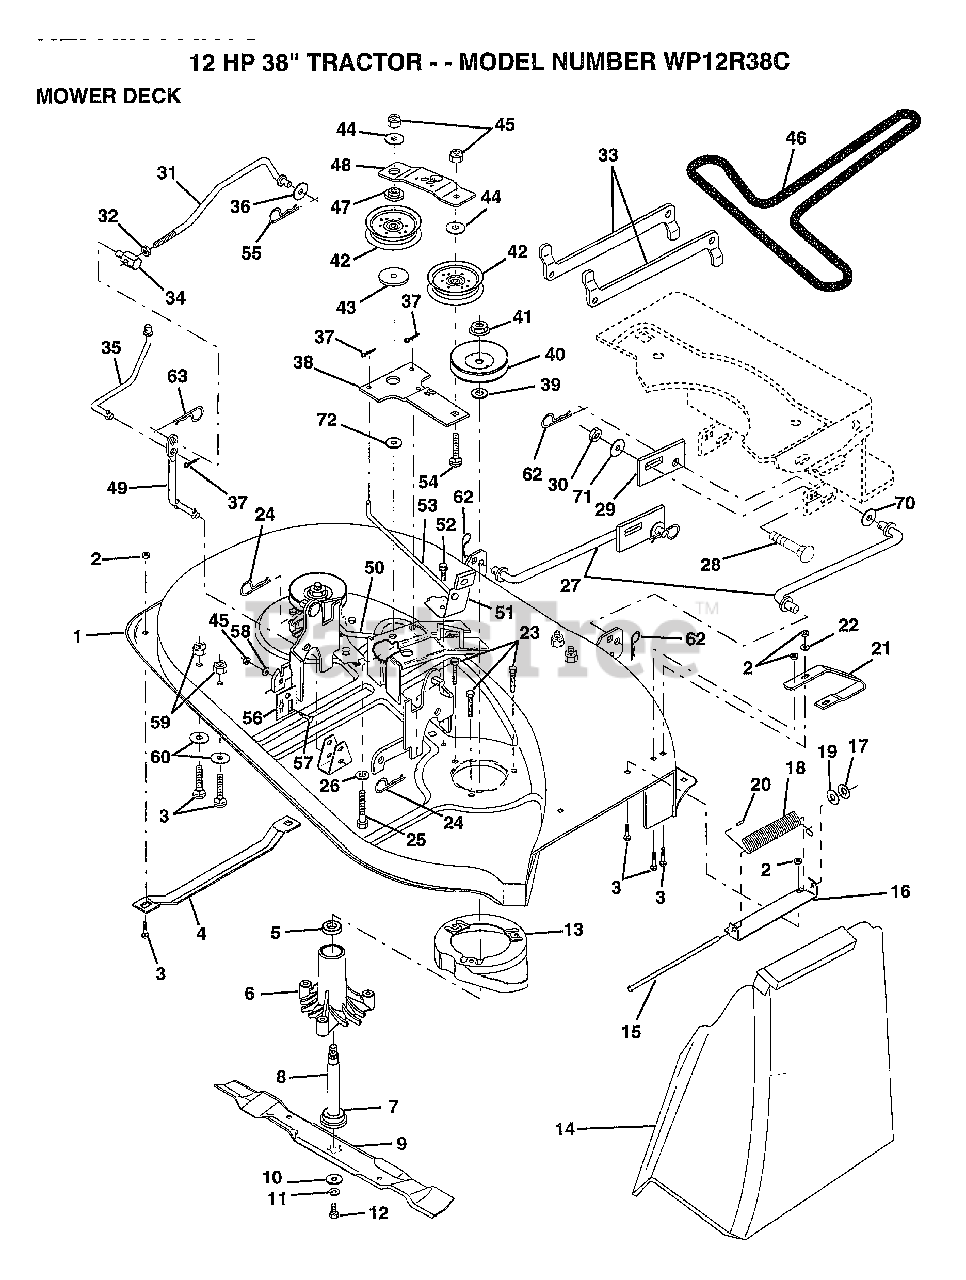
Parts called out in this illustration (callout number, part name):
1	MOWER.WELD.LR.38
2	NUT
3	BOLT
4	RUNNER-LH M
5	BEARING
6	HSG ASM MANDREL
7	BEARING.BALL
9	"BLADE.38""V.MULCH"
10	WASHER.HARD.BLADE
12	BLADE BOLT
14	DEFLECTOR-SHLD T
15	ROD-HINGE T
16	BRKT DEFLECTOR
17	NUT PUSH M
18	SPRING TORSION
19	WASHER
20	CAP-SLEEVE LT
21	RUNNER RH
22	WASHER M
23	BOLT.5/16-18X1.25
25	BOLT
26	WASHER GT
27	"LINK LIFT 38"""
29	PLATE SLIDE LINK
30	NUT
31	ROD.CLUTCH.PRIM
32	NUT
33	SUSP ARM REAR
34	TRUNNION
35	CLUTCH ROD SEC
36	WASHER
38	IDLER ARM ASSY
39	WASHER
42	FLAT IDLER PULLEY
43	SPACER RETAINER
44	WASHER GT
45	NUT
46	V BELT
47	RETAINER SPACER
48	IDLER ARM STIFF
49	PIVOT ROD
50	BRAKE ROD LH
51	BRAKE ASM
52	SCREW
53	BRAKE ROD RH
54	BOLT
55	SPRING.RETAINER
56	PLATE ADJ LINK LH
58	WASHER T
59	NUT
60	WASHER.34X.68X16
62	RETAINER.SPRING
63	RETAINER M
70	WASHER 1/2X1 1/4
71	WASHER PM
72	HARDENED WASHER
